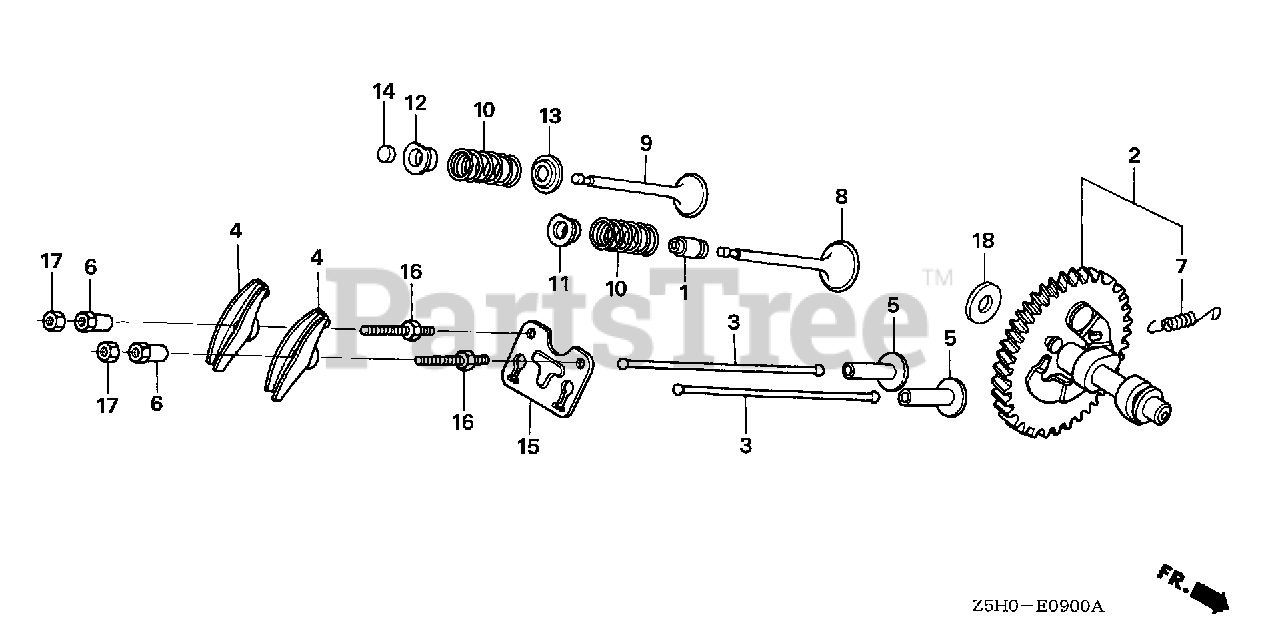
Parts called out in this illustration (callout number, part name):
1	SEAL, VALVE STEM
2	CAMSHAFT ASSY.
4	ARM, VALVE ROCKER
5	LIFTER, VALVE
6	PIVOT, ROCKER ARM
7	SPRING, WEIGHT RETURN
8	VALVE, IN.
9	VALVE, EX.
10	SPRING, VALVE
11	RETAINER, IN. VALVE SPRING
12	RETAINER, EX. VALVE SPRING
13	SEAT, VALVE SPRING
14	ROTATOR, VALVE
15	GUIDE, PUSH ROD
16	BOLT, PIVOT (8MM)
17	NUT, PIVOT ADJUSTING
18	WASHER, THRUST (16.1MM)
